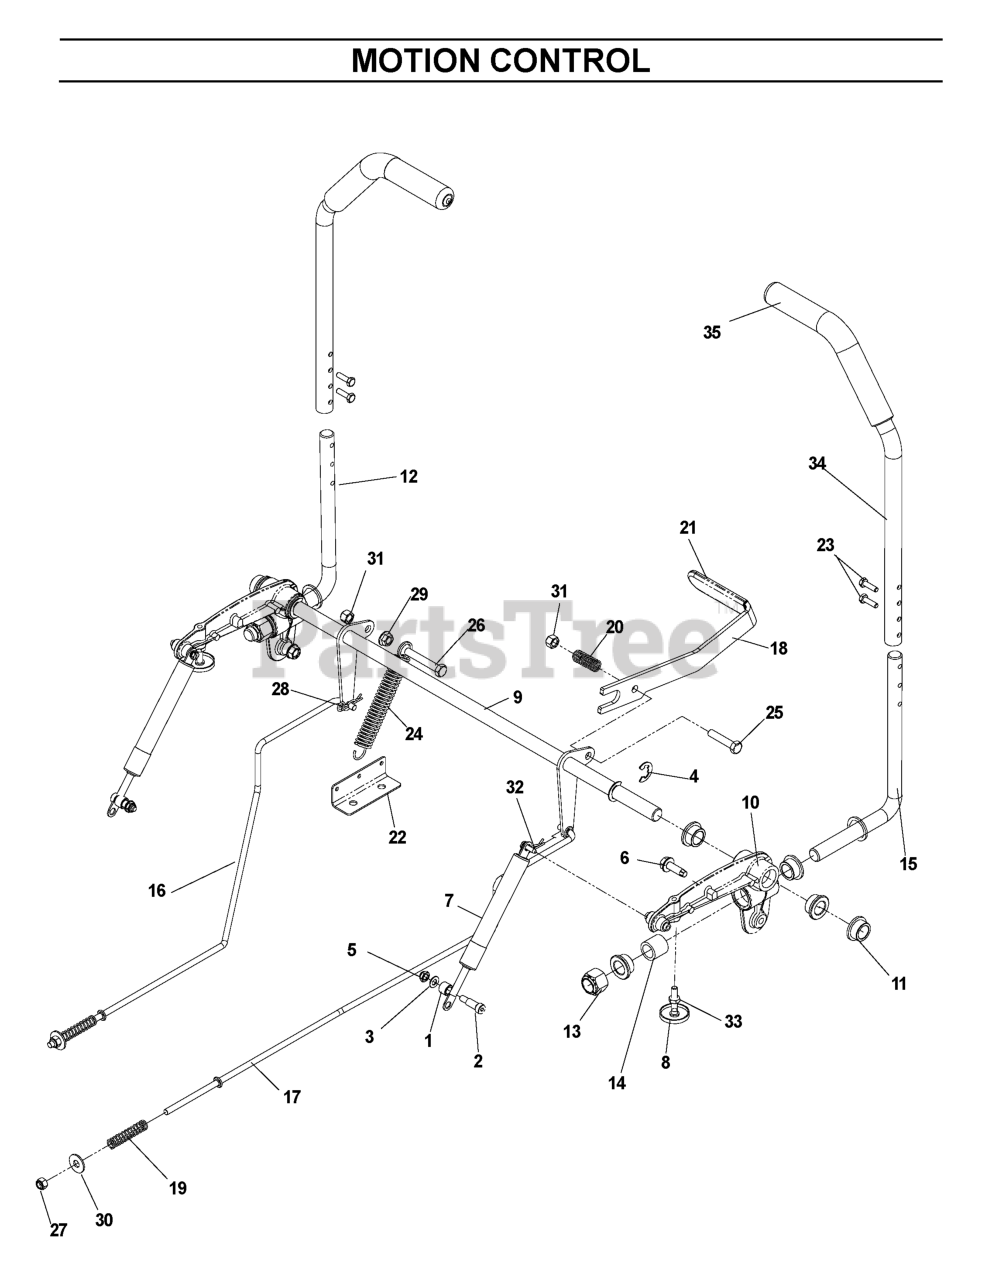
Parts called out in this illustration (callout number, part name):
1	CABLE.DRIVE.21.RWGD.
2	BAIL.CONT.DR.21.RWGD.BLACK
3	DOWNSTOP BRACKET
4	SCREW.HEX.HEAD.WASHER.10-16
5	DRIVE COVER
8	FLANGED LOCKNUT 3/8-16 ZINC
10	BELT GUIDE
11	Screw, Hex Washer Head #10-24 x .668
13	TRANSMISSION.ASSEM.NLA
14	PIN.SPRING.THRUST
15	THRUST WASHER
16	ROD
17	SPRING
18	SPRING
19	KNOB
21	RP BEARING SUPPORT
22	BEARING.BALL.DOUBLE.SEAL
23	BRACKET
25	DRIVE PAWL
26	DRIVE PINION RH
27	PINION.DRIVE.LH
28	E-RING 7/16 RE
29	DUST SHROUD PM
30	WASHER FLUT
32	WHEEL ASSY
33	HEX FLANGE LOCKNT
34	HUBCAP.8".GREY
35	SHAFT ASSY
36	SHAFT ASSY
37	RETAINER.FRONT.SHAFT
39	RETAINER CLIP
40	WHEEL.8X2.PR.LP.RAD.GREY
42	HEX FLANGE LOCKNT
43	WASHER.ZINC.PLATED
44	WAVE WASHER
